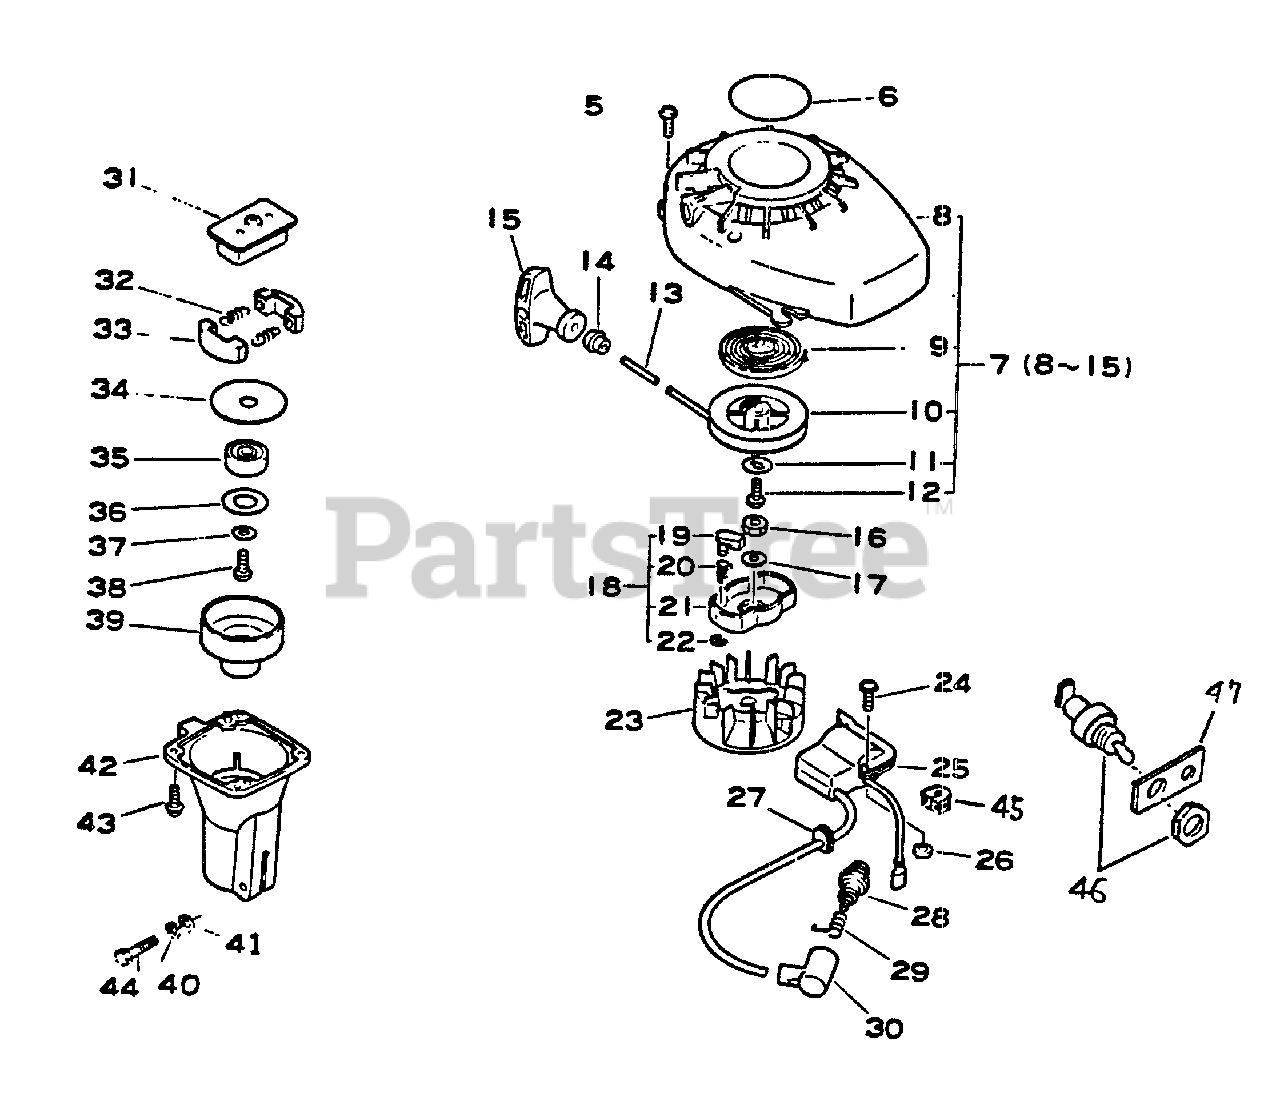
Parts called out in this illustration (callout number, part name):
5	SCREW 4×15
7	STARTER ASSY
8	CASE, STARTER
9	SPRING, RECOIL
10	REEL, ROPE
11	WASHER
13	ROPE, STARTER
14	GUIDE, ROPE
15	GRIP, STARTER
17	WASHER 8.5×16×1.2
18	STARTER PAWL ASSY
19	PAWL, STARTER
20	SPRING, RETURN
21	CATCHER, PAWL
22	RING, RETAINING - 6
23	FLYWHEEL
24	SCREW 4×22
25	COIL, IGNITION
28	SPARK PLUG - CJ-8Y
29	TERMINAL, SPARK PLUG
30	CAP, SPARK PLUG
31	HUB, CLUTCH
32	SPRING, CLUTCH
33	SHOE, CLUTCH
34	PLATE, CLUTCH
35	BEARING, BALL 6000DDU
37	WASHER 6
38	SCREW 6×12
39	DRUM, CLUTCH
40	WASHER, SPRING 5
41	WASHER, FLAT 5.5×10×0.8
42	CASE, CLUTCH
43	SCREW 4×14
44	BOLT - 5×25
46	LEAD
50	COIL, IGNITION
